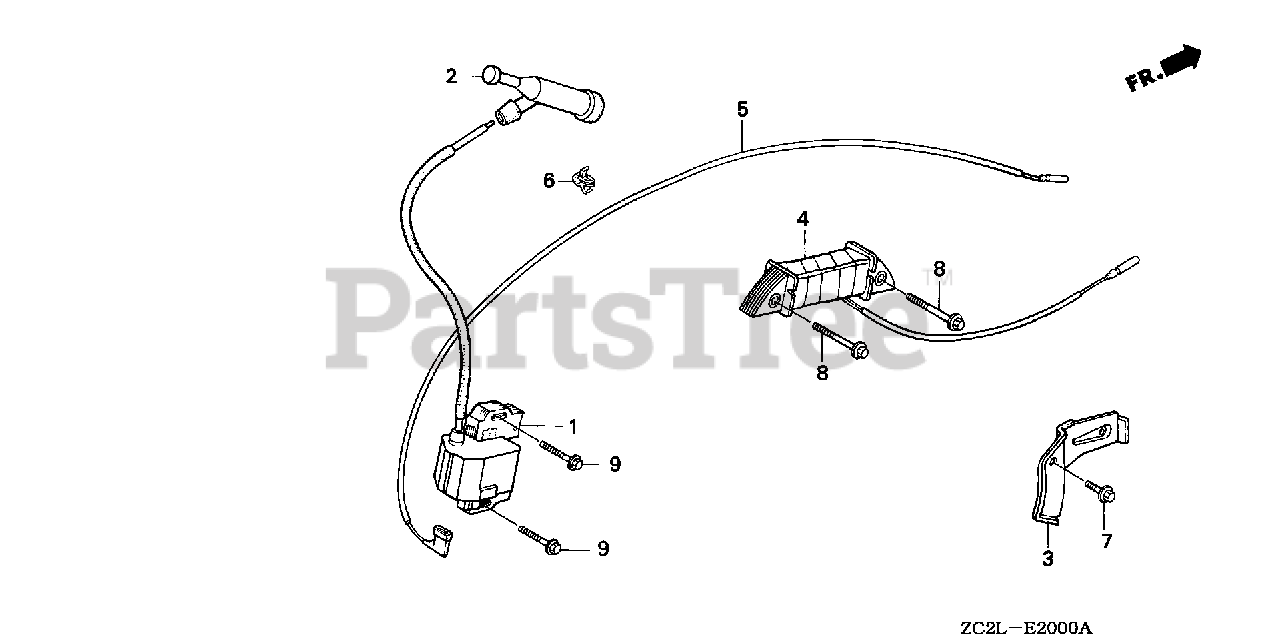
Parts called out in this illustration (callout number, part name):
1	COIL ASSY., IGNITION
2	CAP ASSY., NOISE SUPPRESSOR (NICHIWA Y-EZ RTFM256)
3	CLAMP, WIRE
4	COIL ASSY., CHARGE (1A)
5	WIRE, STOP SWITCH (470MM)
7	BOLT, FLANGE (6X12) (CT200)
8	BOLT, FLANGE (6X35) (CT200)
9	BOLT, FLANGE (6X28) (CT200)
